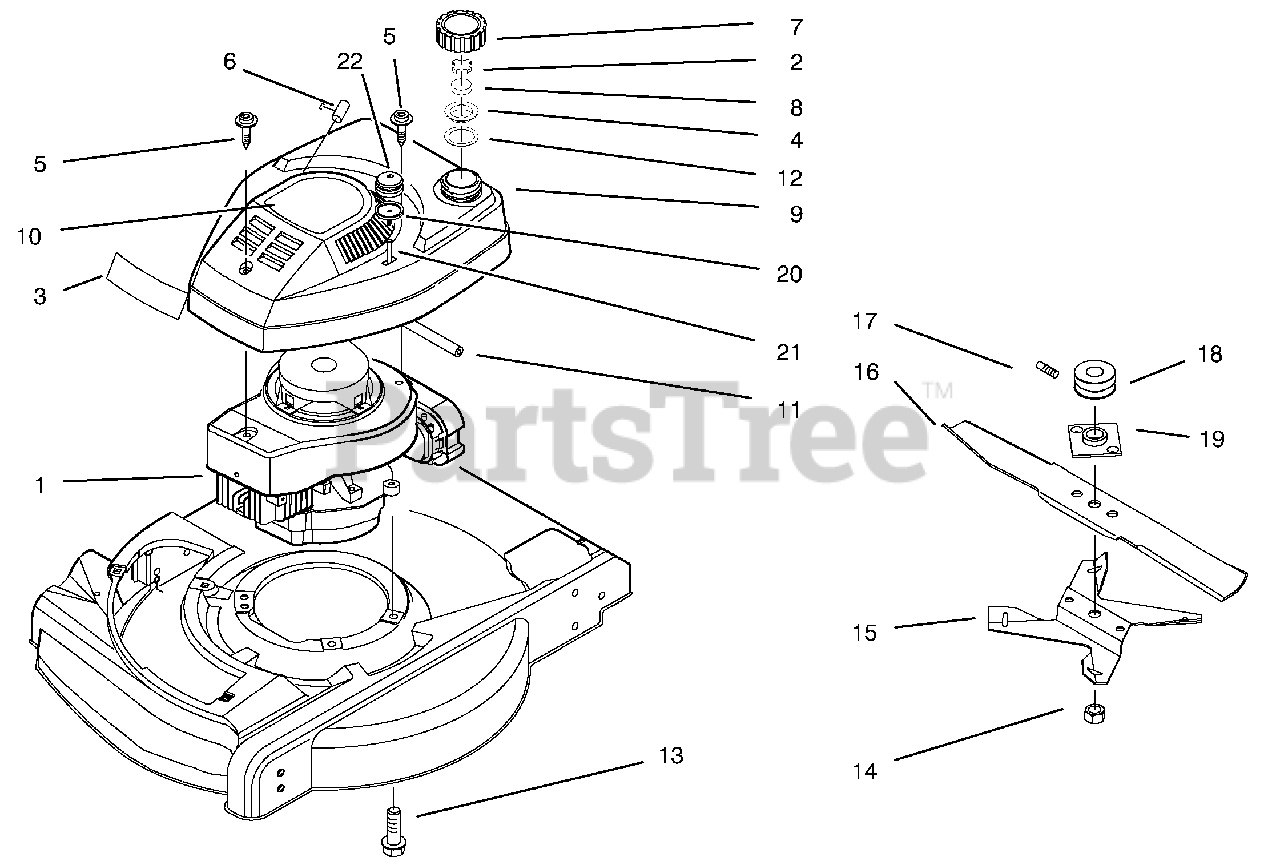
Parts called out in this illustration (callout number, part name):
1	Engine Ass'y-2 Cycle
3	Applique
6	Stop-Rope
7	Cap Assembly-Fuel (Includes Ref. #2, 4, 8, & 12)
8	Baffle-Foam
9	Shroud & Tank Ass'y
10	Decal-Shroud (Model No. 10201 Only)
11	Hose-Gas
13	Screw-Engine Mount
14	Nut-Blade
15	Fan-Mulching
16	Blade-21"
17	Screw-Set, Pulley
18	Pulley-Engine
19	Plate & Collar Ass'y
20	Body-Primer
21	Hose-Primer
22	Bulb-Primer
